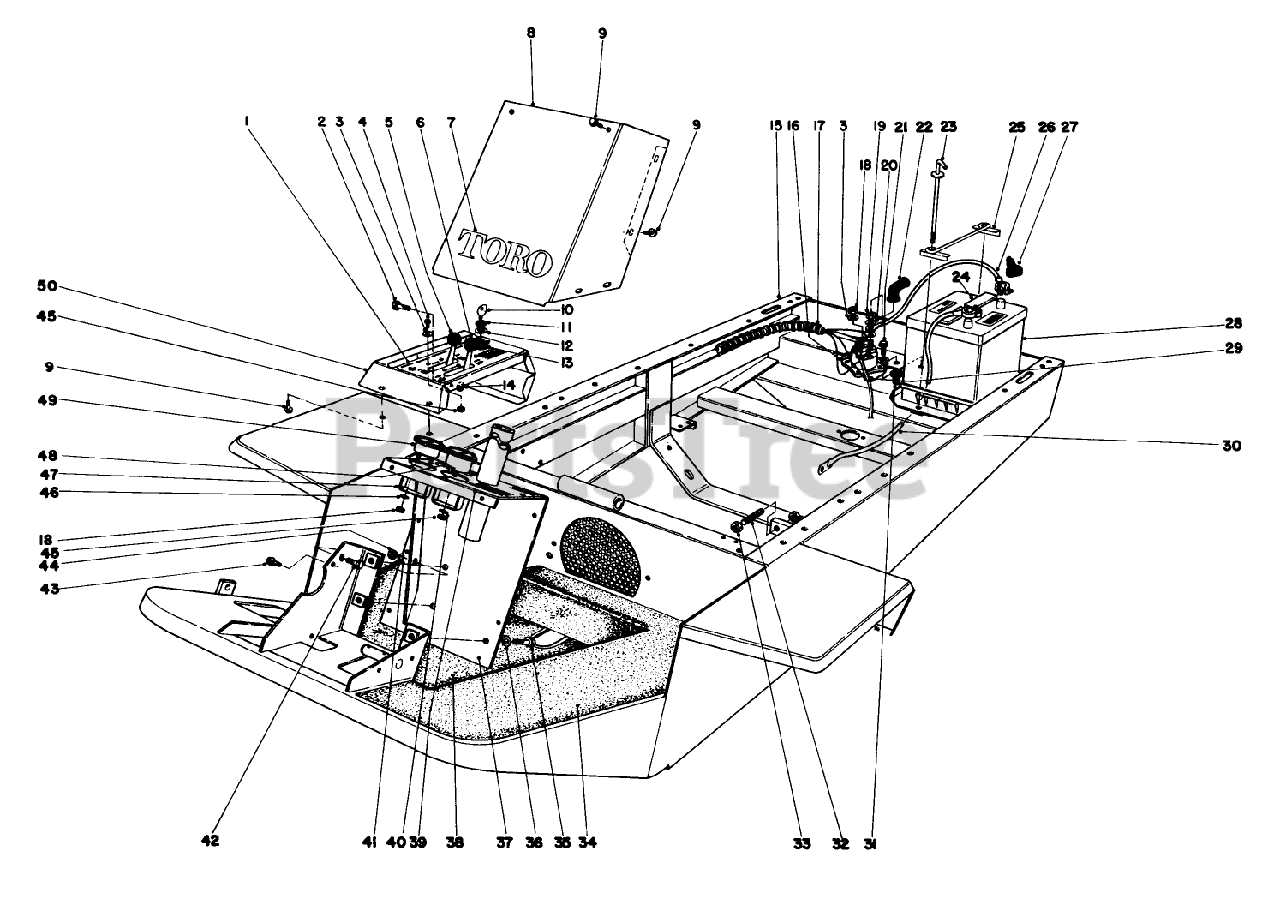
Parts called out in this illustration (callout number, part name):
1	Decal-Instrument Panel
2	SCREW-HH
3	WASHER-LOCK
4	10-24 X 5/8 PAN HD MS
5	CHOKE CONTROL
6	Throttle Control
7	DECAL
8	Cover-Tower
9	SCREW-THD FRM,HWH
10	Key
11	NUT-HH
12	Lockwasher
13	SWITCH-STARTER
14	WASHER-FLAT
15	Frame
16	SOLENOID
17	WIRE HARNESS
18	NUT-HEX
19	NUT-JAM, BRASS
20	WASHER-LOCK
21	SCREW-HH
22	BATTERY BOOT
23	BATTERY BOLT WA B
24	PUSH-ON BATTERY CAP
25	BATTERY HOLD DOWN WA
26	BATT/SOLENOID WIRE
27	BOOT-CABLE, BATTERY
28	Battery
29	SOLENOID TO START WIR
30	BATTERY GROUND WIRE
31	NUT-INSERT
32	STOP PIN PP
33	NUT-JAM
34	NON SKID (TUNNEL)
35	SCREW-HH
36	WASHER-LOCK
37	Steering Post
38	NON-SKID-FLOOR
39	Decal Instruction
40	WASHER-LOCK, INT
41	WASHER-LOCK
42	SCREW-HH
43	SCREW-HWH
44	NUT-HEX
45	NUT-HEX
46	WASHER-FLAT
47	MTG CLAMP F/W GUAGE
48	HOUR METER
49	AMMETER GAUGE ASSY
50	Instrument Panel
